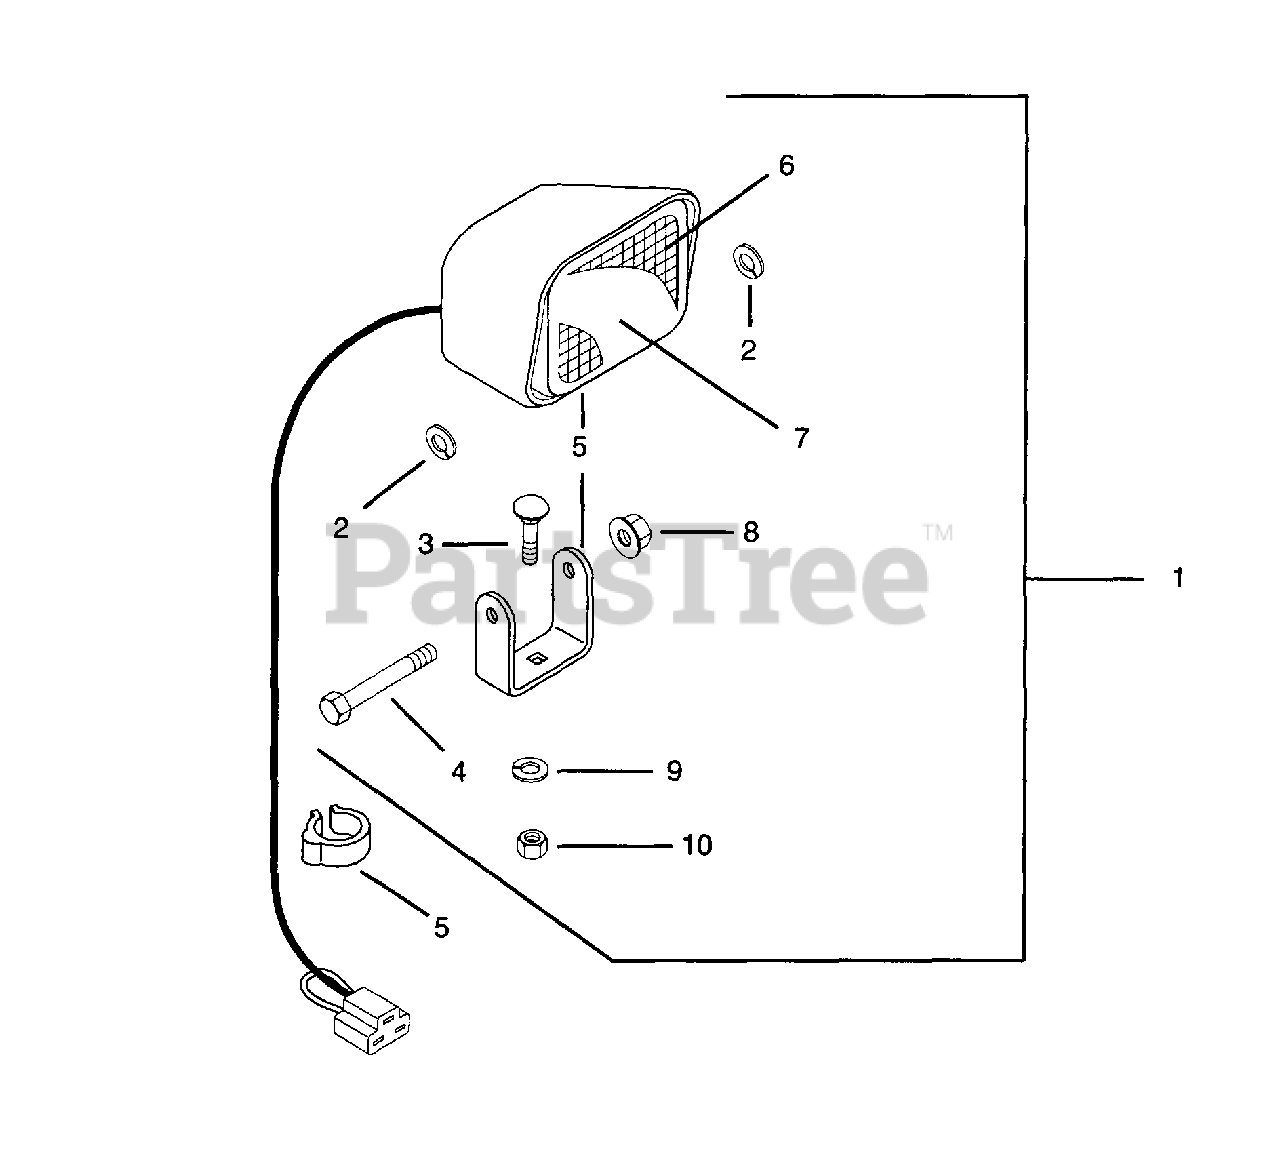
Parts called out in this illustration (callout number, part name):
1	HEADLIGHT
2	@WSHR-LK-EXT.326X.599X.031YWZC
3	BLT-RDHDSQNK .31-18X1.00 PL
4	BLT-HEX .31-18X2.50 PL GR2
6	LENSE-FLOOD
8	@NUT-SPNLK-FLG .312-18 YWZC
9	WSHR-LK .312X.097 HVY YWZC
10	@NUT-HEX .31-18 YWZC
